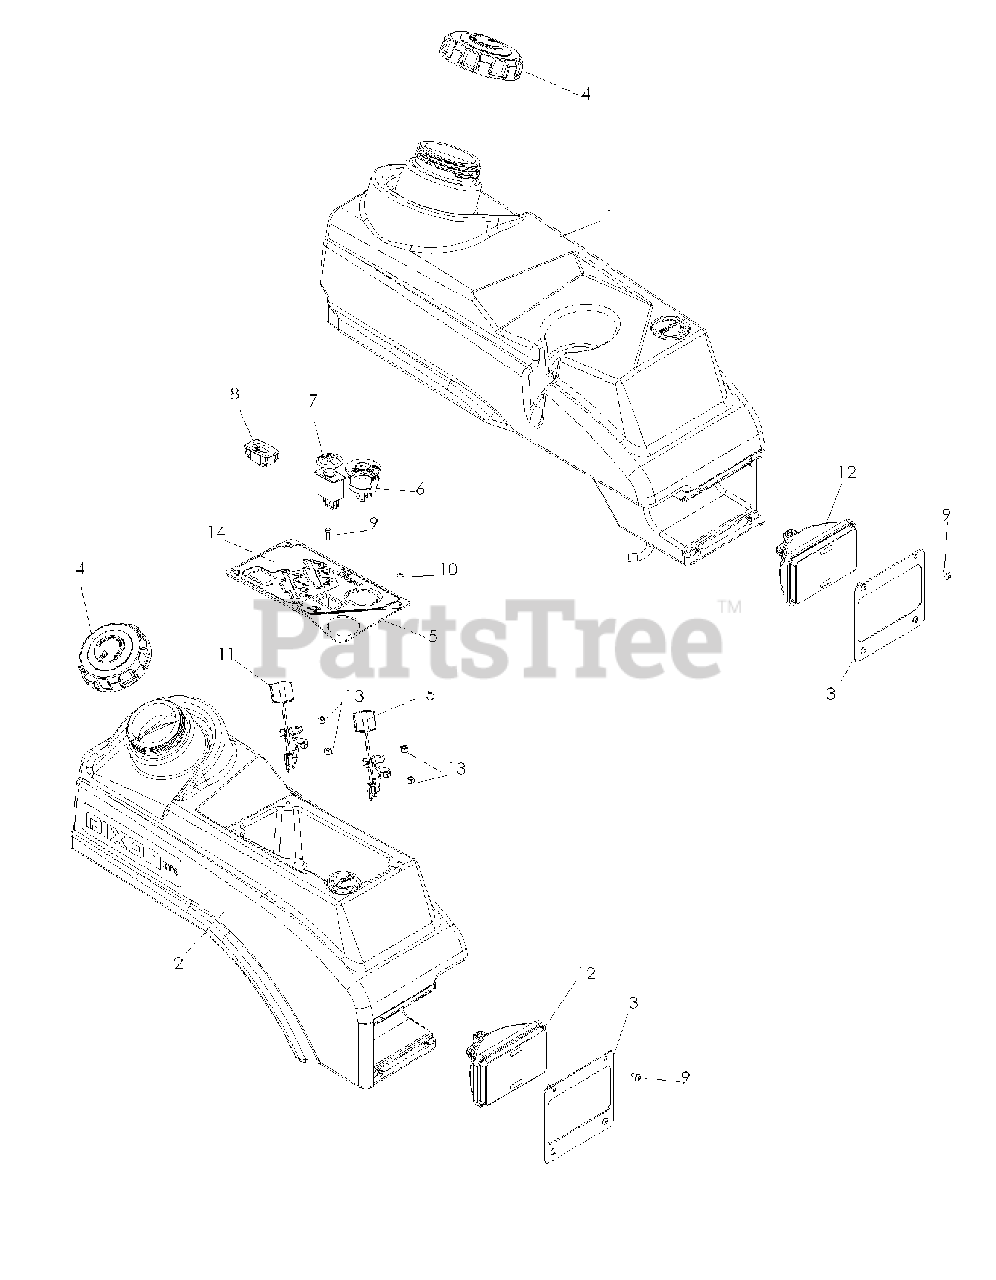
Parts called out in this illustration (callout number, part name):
1	TANK, FUEL, LT
2	TANK, FUEL, RT
3	PLATE LIGHT
4	FUEL CAP ANTI-SPLASH
5	CONTROL PANEL
6	IGNITION SWITCH
7	SWITCH, BLADE
8	HOUR METER
9	HCS #10-24 X 1/2
10	SCR #10-24 X 3/8 SKT HD BLK OX
11	CABLE THROTTLE
13	NUT 10-24 NYLOC
14	DECAL, CONTROL
15	CHOKE CABLE
